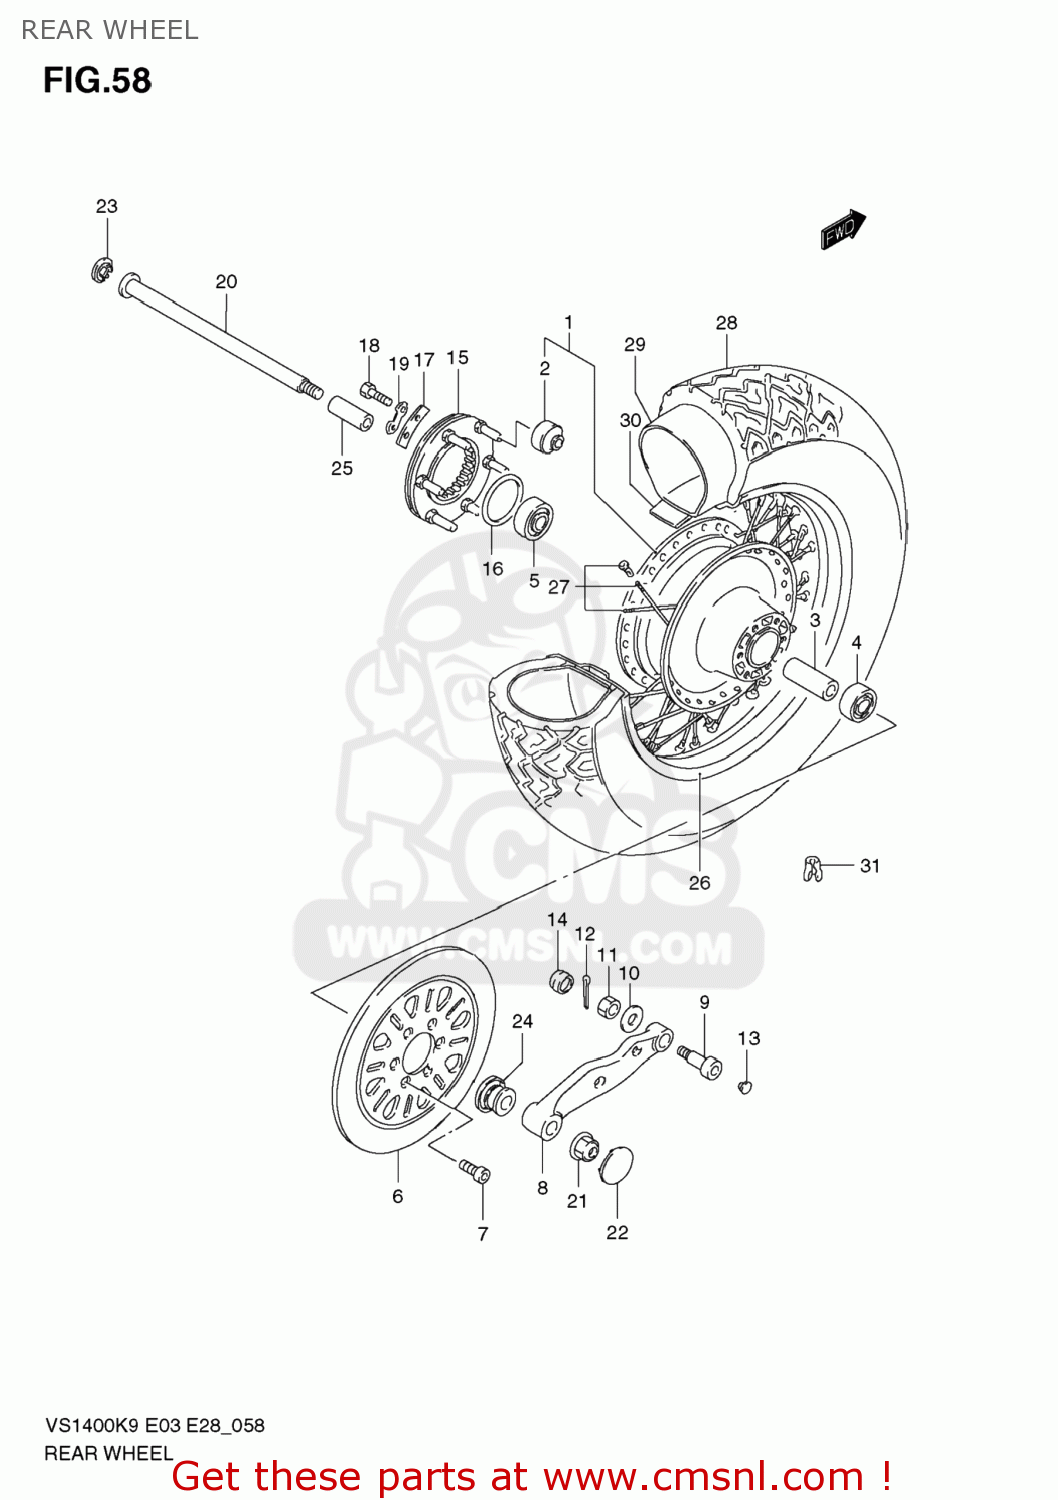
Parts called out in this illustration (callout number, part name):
1	HUB SET,RR
2	BUSH
3	SPACER(17.5X25X113)
4	BEARING
5	BEARING
6	DISC,RR BRAKE
7	BOLT(8X33)
8	BRACKET,RR CALIPER
9	PIN,CALIPER BRACKET
10	WASHER(12.5X24X2.6)
11	NUT
12	PIN
13	CAP(OD:12)
14	CAP
15	JOINT ASSY,RR HUB DRIVEN
16	O RING(D:2.1,ID:65)
17	WASHER,THRUST(T:1.6)
18	BOLT(6X16)
19	WASHER
20	AXLE,RR
21	NUT
22	CAP,RR AXLE,R
23	CAP,RR AXLE,L
24	SPACER,RR AXLE,R
25	SPACER(17.3X25X79.5)
26	RIM,RR WHEEL MT(4.00X1.5)
27	SPOKE SET,RR WHEEL
28	TIRE,RR(170/80 15M/C 77H)
29	TUBE ASSY,WHEEL INNER
30	PROTECTOR, INNER TUBE
31	BALANCER,WHEEL(30G)
